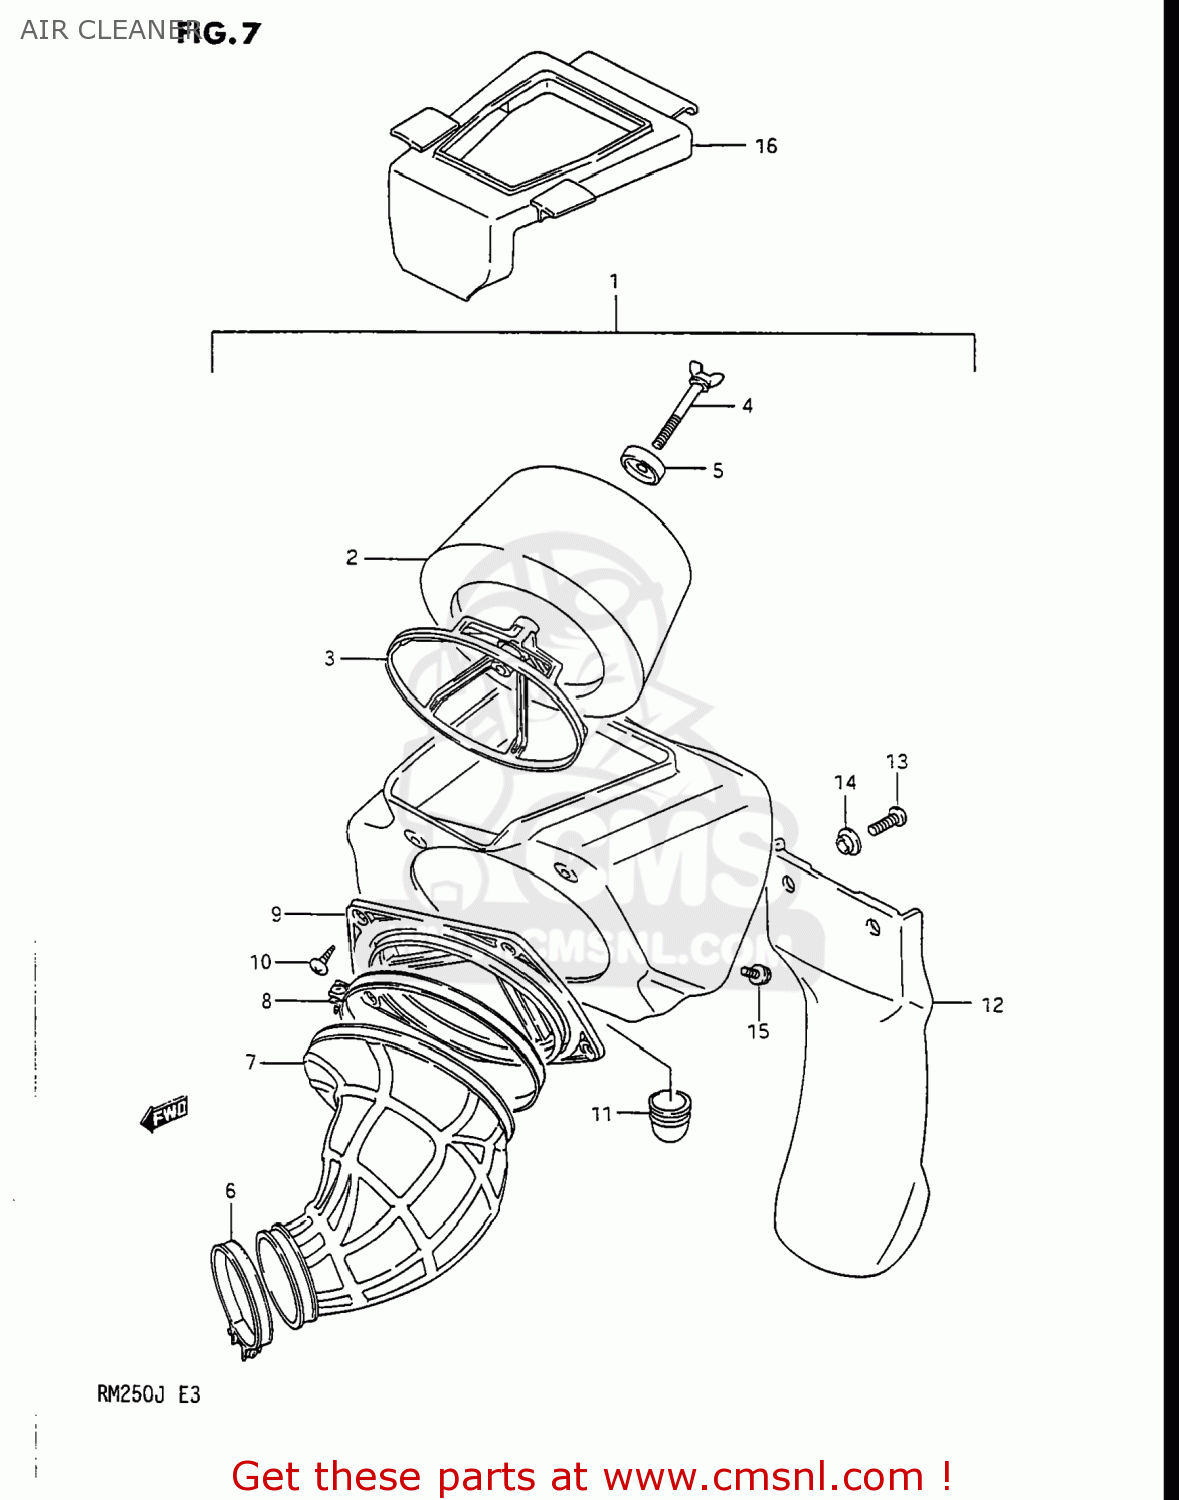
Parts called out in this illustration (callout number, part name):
1	CLEANER ASSEMBLY,AIR (ASB)
2	FILTER,AIR CLEANER
3	HOLDER,FILTER
4	BOLT,WING
5	WASHER,AIR CLEANER
6	CLAMP
7	TUBE,AIR CLEANER OUTLET
8	CLAMP
9	HOLDER,FILTER
10	SCREW
11	TUBE,DRAIN
12	GUARD,MUD
13	SCREW
14	COLLAR
15	BOLT
16	MUD GUARD,B
